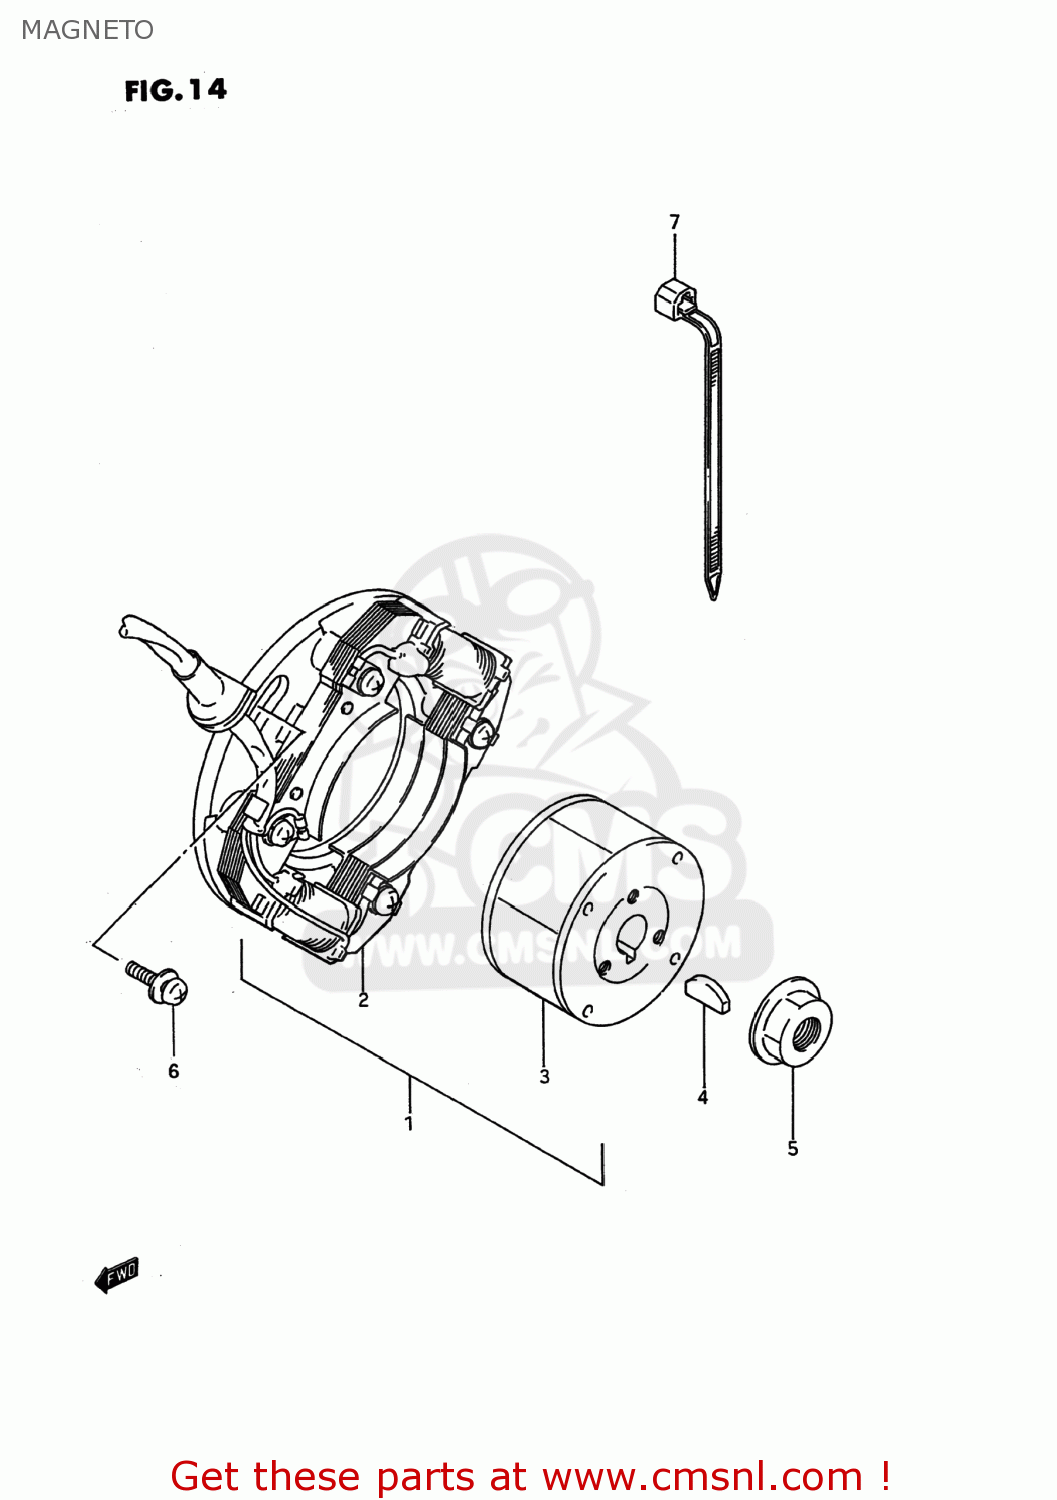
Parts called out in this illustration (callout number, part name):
1	MAGNETO ASSEMBLY
2	STATOR ASSEMBLY
3	ROTOR
4	KEY
5	NUT
6	SCREW
7	CLAMP L:165
